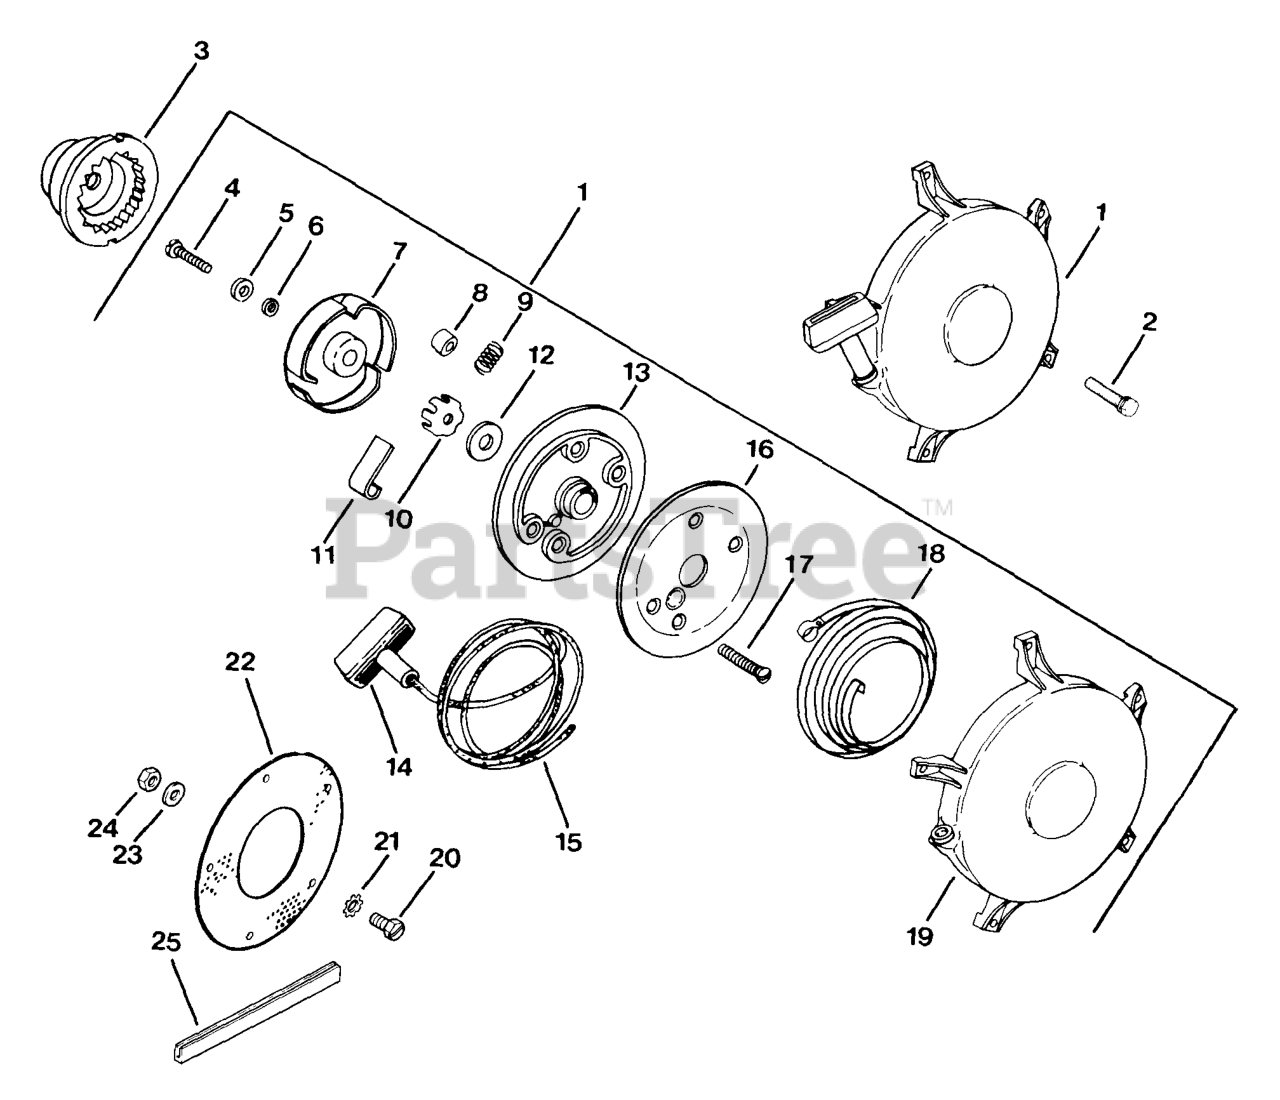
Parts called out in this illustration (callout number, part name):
1	STARTER
3	CUP, DRIVE - DISCONTINUED
5	WASHER - DISCONTINUED
7	RETAINER
9	SPRING - DISCONTINUED
9	SPRING
11	DOGS - DISCONTINUED
14	HANDLE - USE 25 166 01
19	HOUSING - DISCONTINUED
